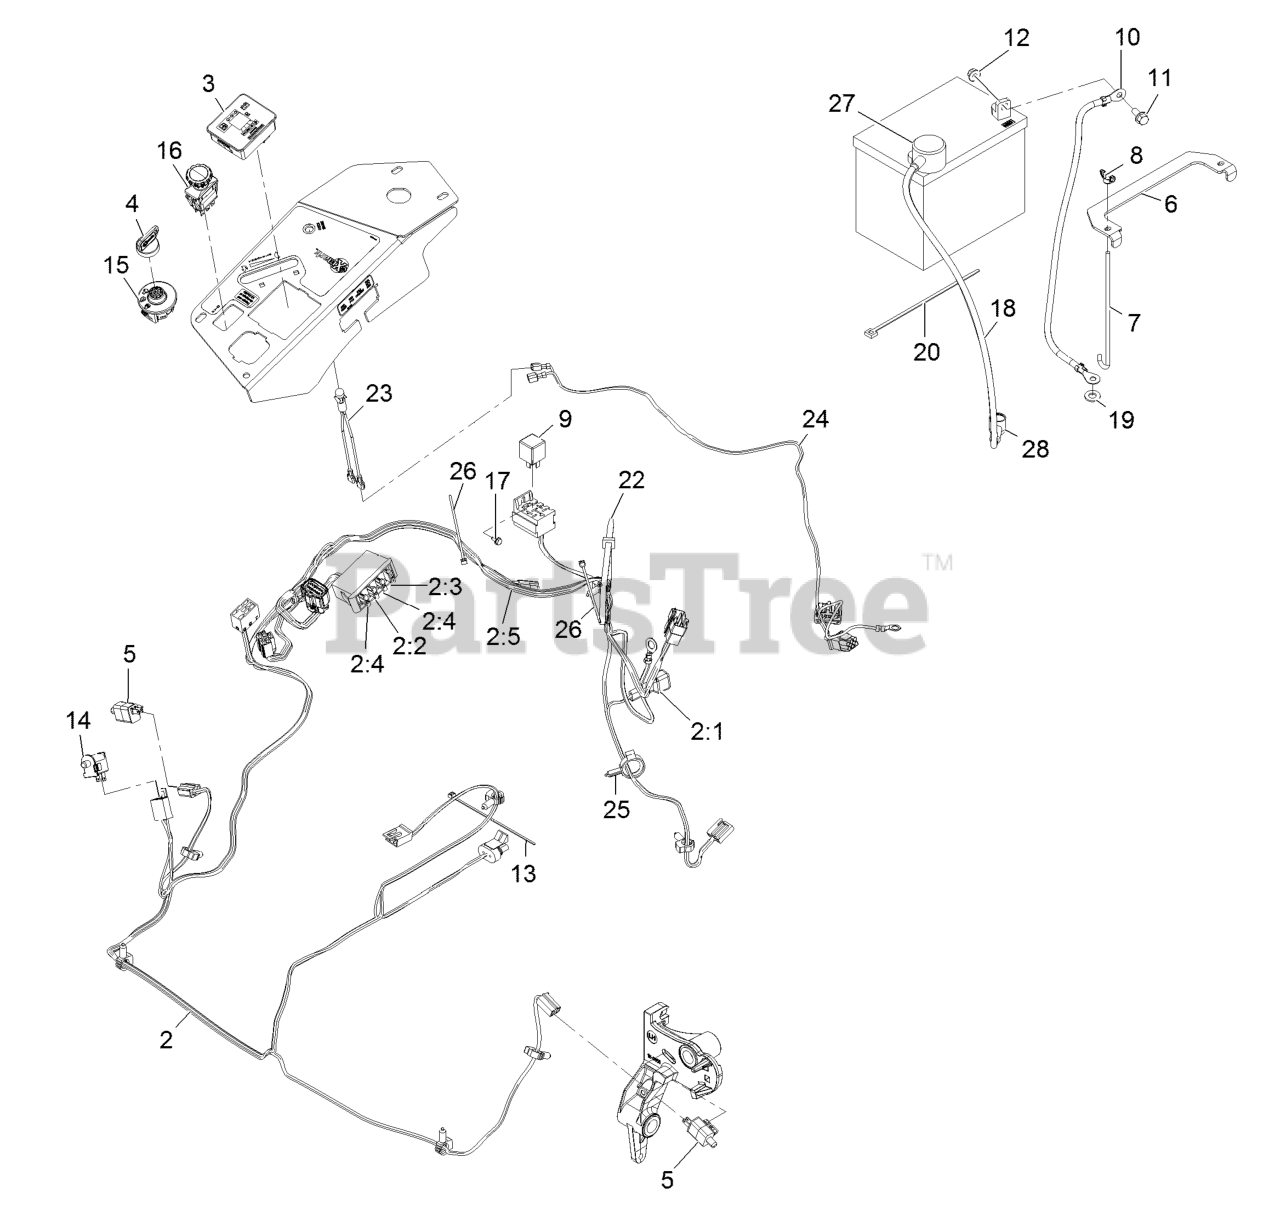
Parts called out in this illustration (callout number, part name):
2	HARNESS-WIRE, MAIN
2:2	FUSE-BLADE, 10 AMP
2:3	FUSE-BLADE, 15 AMP
2:4	FUSE-BLADE, 25 AMP
2:5	CAP-PLUG
3	FUEL/HOUR METER ASM
4	KEYS-IGNITION (SPARE PAIR
4	KEY-IGNITION
6	STRAP-TIE DOWN, BATTERY
7	BOLT-HOLDDOWN
8	WINGNUT
10	CABLE-BATTERY, NEGATIVE
11	SCREW-HHF
12	NUT-HF, NI
13	TIE-CABLE
14	SWITCH-BAIL
16	SWITCH-PTO, 10 AMP
17	SCREW-HWH
18	CABLE-BATTERY, POSITIVE
19	WASHER-FLAT
20	TIE-PLASTIC
22	TIE-PLASTIC
23	INDICATOR-LED, RED
24	HARNESS-LIGHT, INDICATOR
25	CLAMP-HOSE
26	TIE-CABLE
27	INSULATOR-BATTERY
28	INSULATOR-SOLENOID
